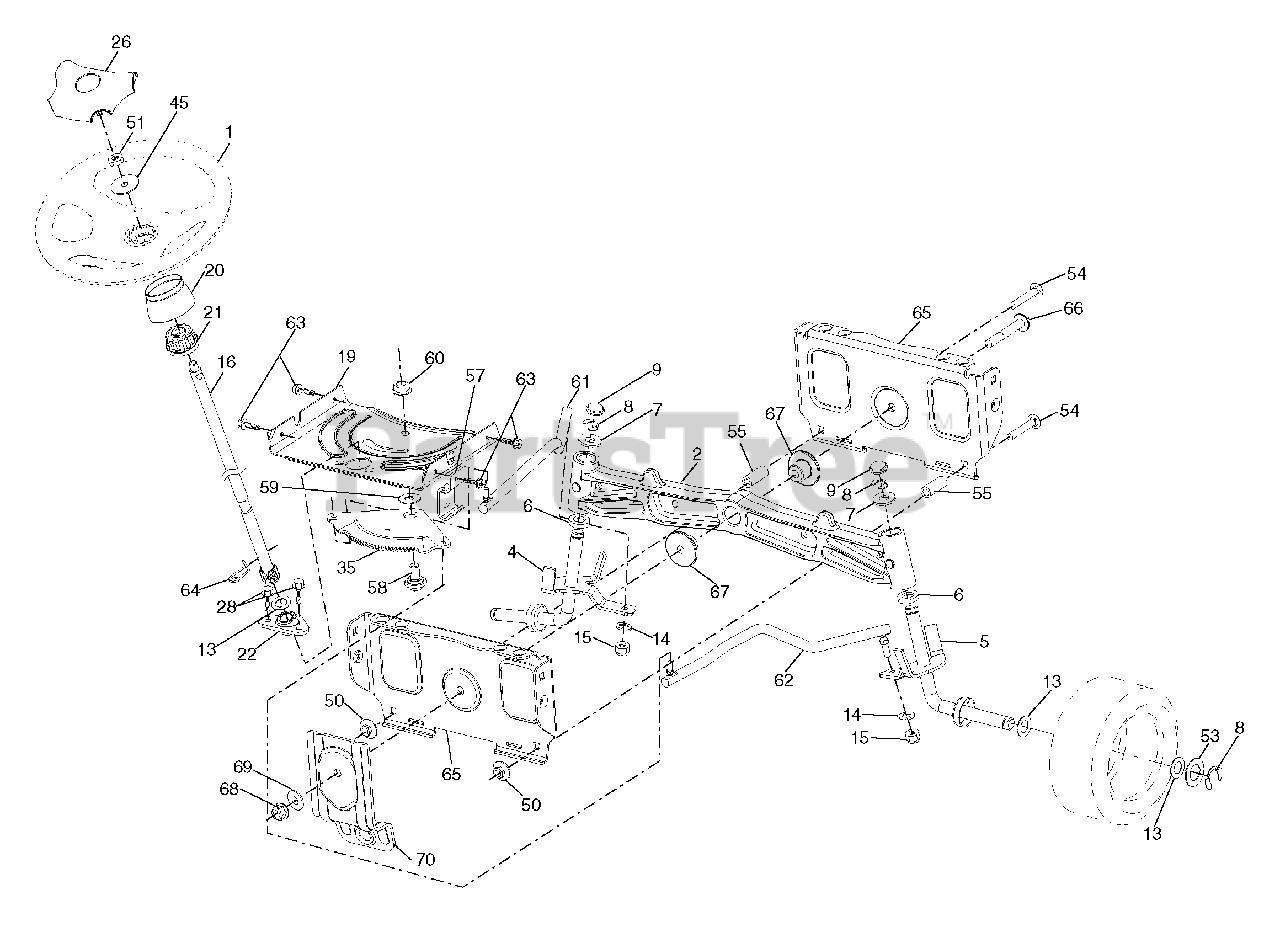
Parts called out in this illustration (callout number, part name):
1	Wheel, Steering
2	Axle Asm., Front
4	Spindle Asm., LH
5	Spindle Asm., RH
6	Bearing, Race Thrust Harden
7	Washer 25/32 x 1-5/8 x 16 Ga.
8	Ring, Klip #T5304-75
9	Cap, Spindle
13	Washer 25/32 x 1-1/4 x 16 Ga.
14	Washer, Lock Hvy Hlcl Spr 3/8
15	Nut, Crown Lock 3/8-24 unf
16	Shaft Steering
19	Plate Steering
20	Boot, Steering
21	Adapter, Wheel Steering
22	Bushing, Strg. Blk
26	Insert, Wheel Steering
28	Screw 3/8-16 x 3/4
35	Gear, Sector Plate
45	Washer 11/32 x 2-3/8 x 12 Ga.
50	Nut Lock 3/8-16 UNC
51	Nut Hex Jam Toplock 1/2-20 unf
53	Washer Hardened .793 x 1.637 x .060
54	Bolt Hex 3/8-16 UNC x 2-1/4
55	Spacer Brace Axle
57	Bracket Upstop
58	Bolt Shoulder Sector Pivot CFM
59	Washer Thrust Sector Steering
60	Nut Flange Lock 5/8-11
61	Draglink LH
62	Draglink, RH
63	Screw 5/16-18 x 3/4
64	Retainer Clip Spring Steering
65	Brace Axle Front
66	Bolt Hex Fghd 7/16-14 x 3 Serr
67	Bushing PM Front Axle
68	Nut Lock Flange 7/16-14 Gr. 5
69	Washer 1.5 x .505 x .118
70	Bracket Deck Susp. Front
